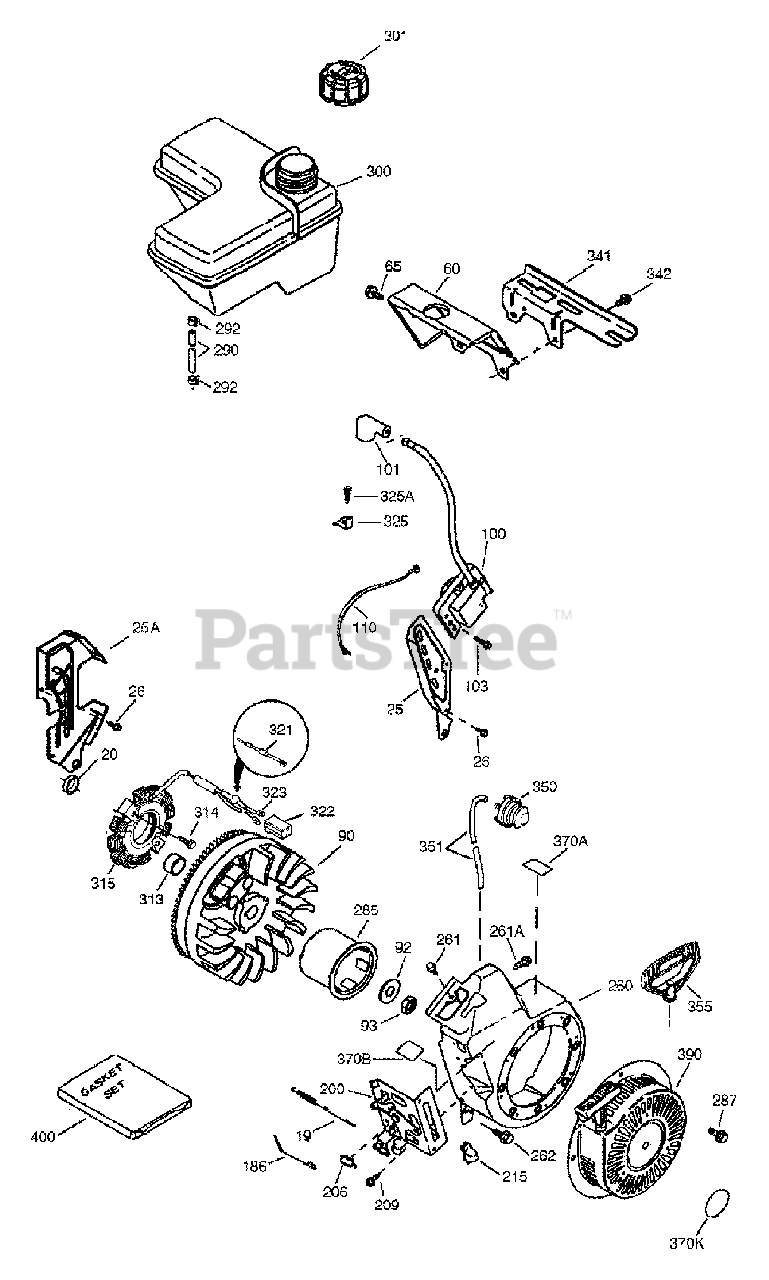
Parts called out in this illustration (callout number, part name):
19	Extension Spring
25	Air Baffle (Left)
25A	Air Baffle (Right)
26	Screw, 10-24 x 9/16"
60	Blower Housing Extension
65	Screw, 10-24 x 9/16"
92	Belleville Washer
93	Flywheel Nut
100	Solid State Ignition
101	Spark Plug Cover
103	Screw, T-15, 10-24 x 15/16"
110	Ground Wire
186	Governor Link
200	Control Bracket
209	Screw, 10-32 x 1/2"
215	Control Knob
260	Blower Housing
261	Screw, 1/4-20 x 31/64"
261A	Screw, 10-32 x 1/2"
262	Screw, 1/4-20 x 31/64"
285	Starter Cup
287	Screw, 1/4-20 x 31/64"
290	Fuel Line (12.62")
292	Fuel Line Clamp
300	Fuel Tank
301	Fuel Cap
314	Screw, 1/4-20 x 3/4"
315	Alternator Coil (18 Watt)
325	Fuel Line Bracket
325A	Screw, 10-24 x 9/16"
341	Fuel Tank Bracket (Lower)
342	Screw, 1/4-20 x 7/8"
350	Primer Assembly
351	Primer Line
355	Starter Handle (Mitten Grip)
370A	Lubrication Decal
370B	Control Decal
370K	Starter Decal
390	Rewind Starter
400	Gasket Set
